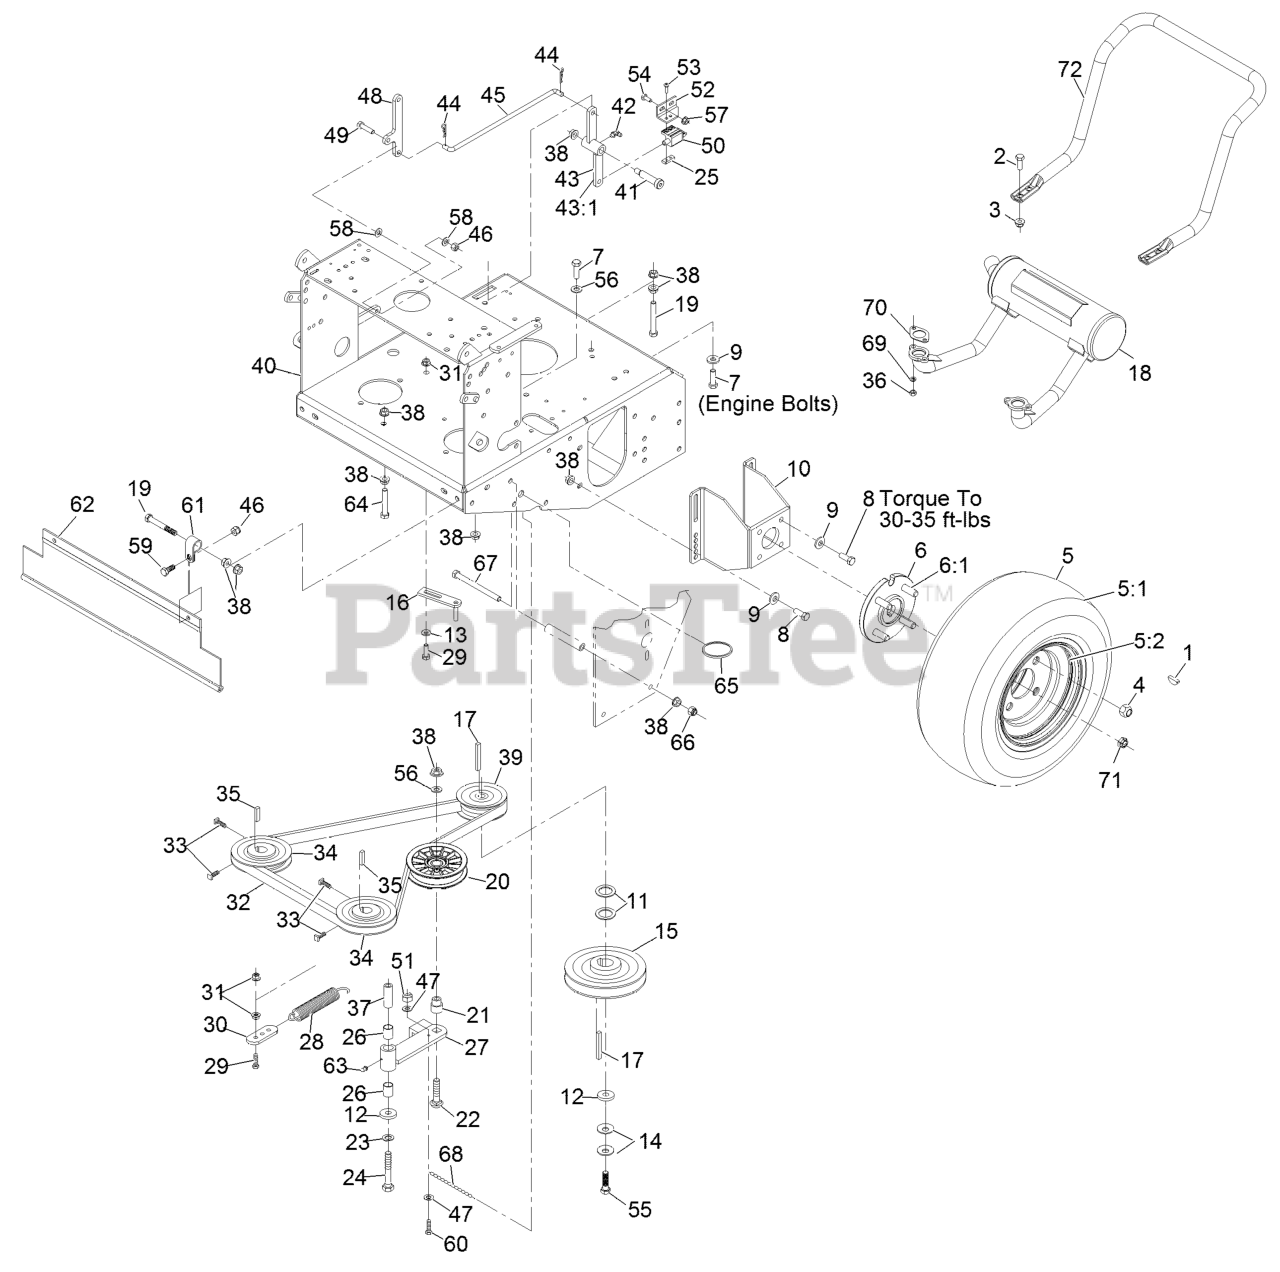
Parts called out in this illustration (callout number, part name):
1	KEY-WOODRUFF
2	SCREW-HH
3	NUT-HF, NI
4	NUT-LUG
5	WHEEL AND TIRE ASM
5:1	TIRE-TURFMASTER
5:2	RIM-WHEEL
6	WHEEL HUB ASM
6:1	STUD-WHEEL
7	SCREW-HH
8	SCREW-HH
9	WASHER-BELLEVILLE
10	MOUNT-MOTOR
11	WASHER-SPACER
13	WASHER-SPRING
14	WASHER-SPRING
16	GUIDE-BELT
18	MUFFLER-HORIZONTAL, OFFSE
19	SCREW-HH
20	PULLEY-IDLER, FLAT
21	BUSHING-IDLER
22	SCREW-CARR
23	WASHER-LOCK
24	BOLT-CARR
25	PLATE-TAPPED
26	SLEEVE-BEARING
27	IDLER ARM ASM
28	SPRING-EXTENSION
29	SCREW-HH
30	ANCHOR-SPRING
32	BELT-COG
33	SCREW-SET
34	SHEAVE ASM
37	BUSHING
38	NUT-HHF, WHIZ
39	PULLEY
40	ASM, VH ENGINE DECK W/DEC
42	FITTING-GREASE, 90 DEG
43	BELLCRANK ASM
44	PIN-COTTER
45	LINKAGE-ENGAGE, BLADE
46	NUT-LOCK, NI
47	WASHER-FLAT
48	BELLCRANK
49	SCREW-HH
50	SWITCH-OPEN, NORMALLY
51	NUT-LOCK, NI
52	BRACKET-SWITCH, BLADE
53	SCREW-PPH
54	SCREW-HH
55	SCREW-HH
56	WASHER-FLAT
58	WASHER-PLAIN
59	SCREW-HH
60	SCREW-HSH
61	CLIP-LOOM
62	SHIELD-DRAG
63	FITTING-GREASE
64	SCREW-HH
65	RING-SPLIT
66	NUT-LOCK, NI
67	SCREW-HH
68	CHAIN-LINK, TWIST
69	WASHER-LOCK
70	GASKET-EXHAUST
71	NUT-LOCK
72	GUARD-MUFFLER
